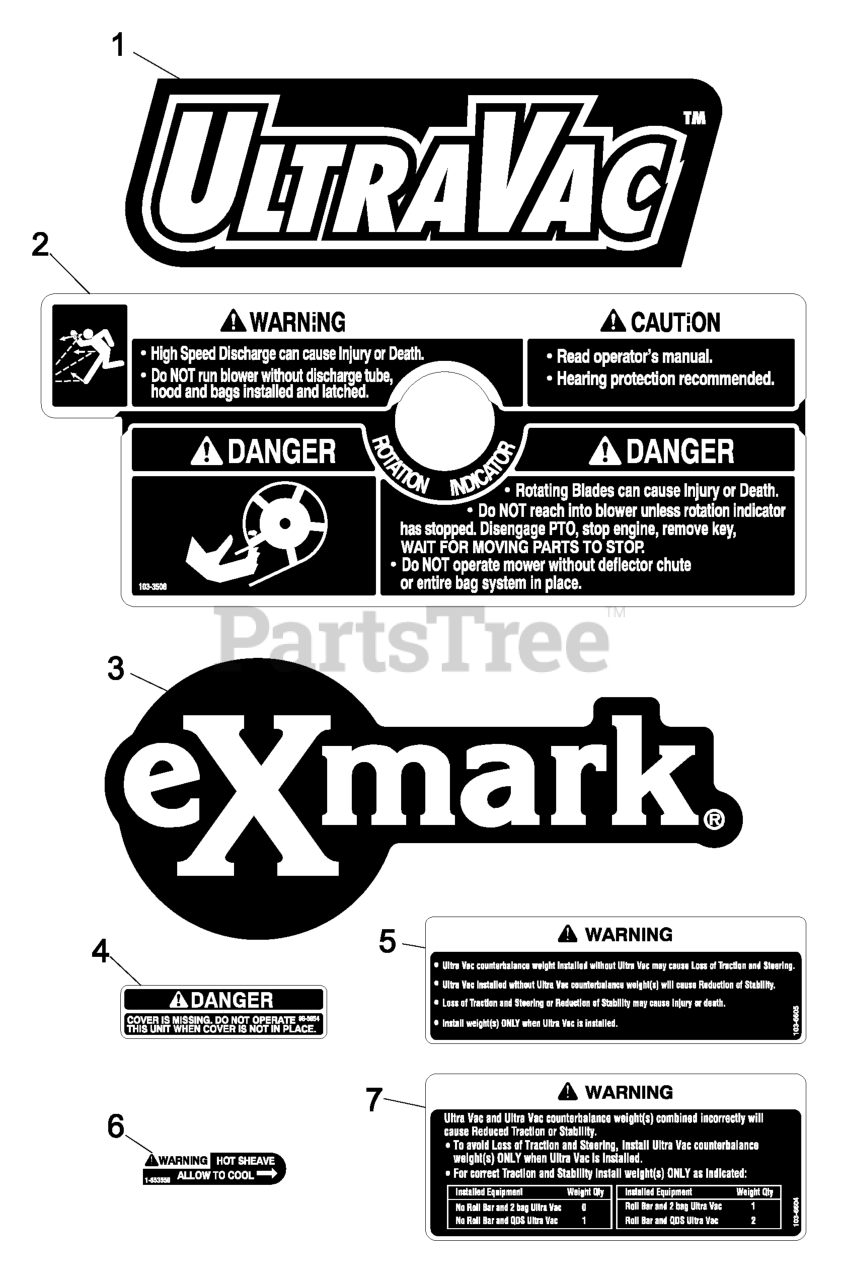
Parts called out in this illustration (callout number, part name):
1	DECAL, ULTRAVAC
2	DECAL-WARNING
3	DECAL, EXMARK LOGO
4	DECAL-COVER, MISSING
5	DECAL,WEIGHT
6	DECAL-WARNING
7	DECAL,WEIGHT
